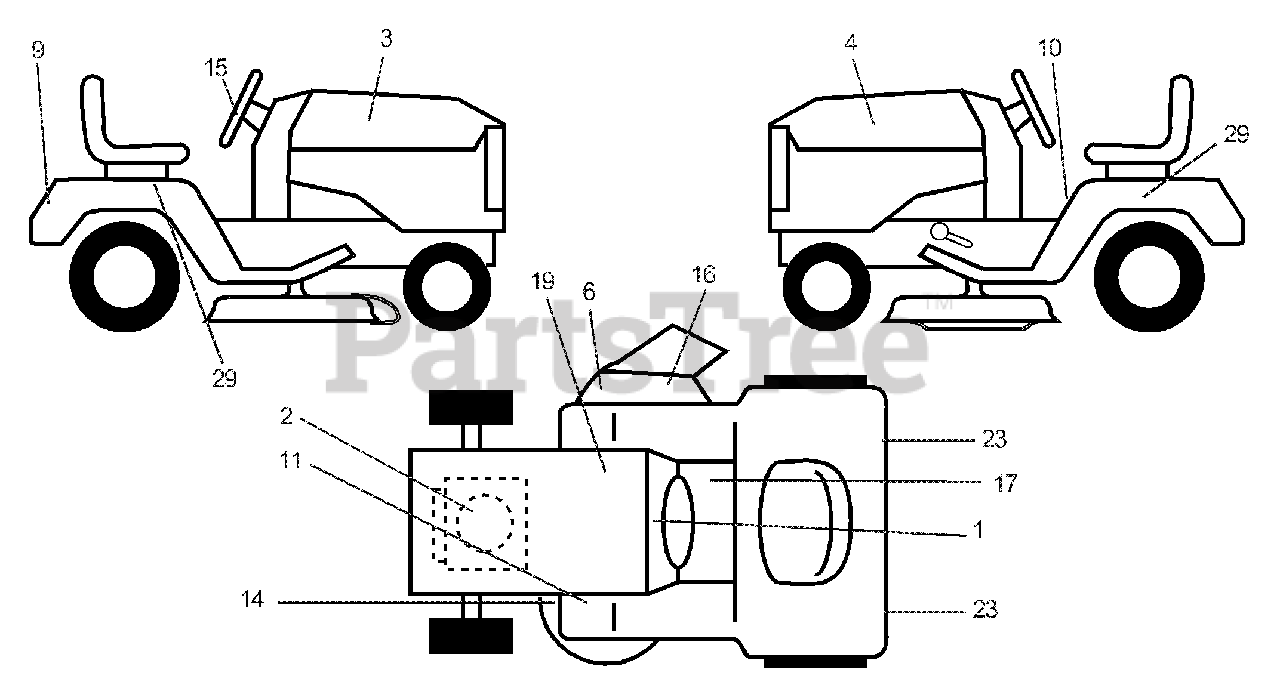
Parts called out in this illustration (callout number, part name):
1	Decal, Dash
2	Decal, Engine
3	Decal, Hood, RH
4	Decal, Hood, LH
6	Decal, Warning
9	Decal
10	Decal, Danger
11	Decal, Clutch/Brake
14	Decal, V-Belt Schematic
15	Decal, Ins. Whl. Strg.
17	Decal, Saddle Brake Parking
19	Decal, Battery
23	Reflector, Taillight
29	Decal, Fender Auto Trans
